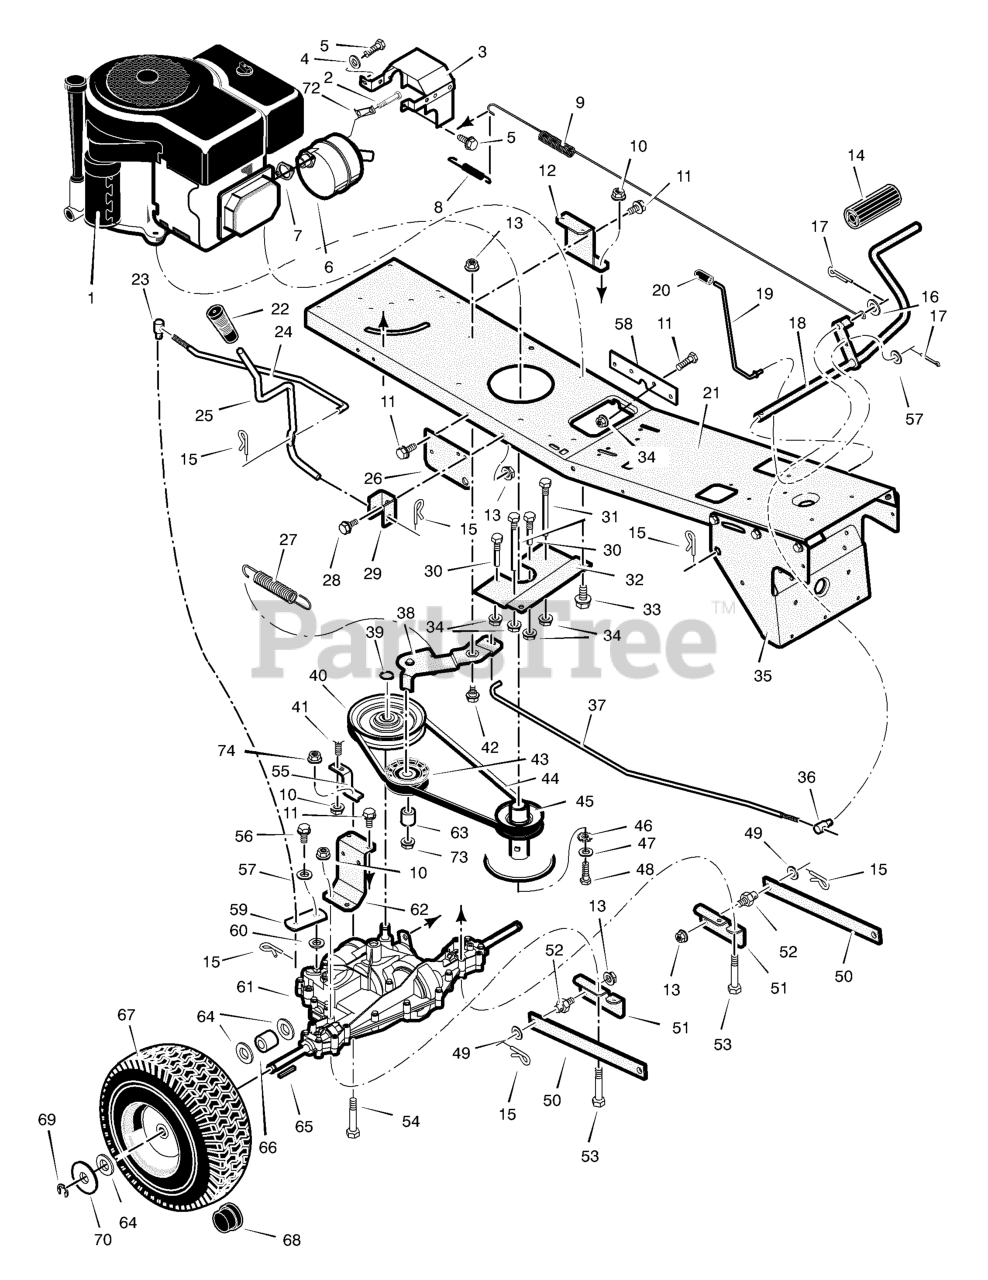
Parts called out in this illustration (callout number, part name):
1	Engine, Briggs & Stratton *
2	Bolt, Hex
3	Shield Assembly, Heat
4	Lockwasher
5	Screw
6	Muffler
7	GASKET, Exhaust
8	Spring, Extension
9	Spring, Extension
10	Nut
12	Bracket, Left Transaxle
13	Nut, Flange
14	Cover, Pedal
15	Pin, Cotter
16	Washer
17	Pin, Cotter
18	Pedal Assembly
19	Rod, Parking Brake
20	Grip, Parking Brake Rod
22	Grip, Shift Lever
23	Nut, Adjusting
24	Link, Shift
25	Lever, Shift
26	Bracket, Lift Pivot
27	Spring, Extension
28	Bolt, Shoulder
29	Bracket, Pivot
30	Guide, Short Belt
31	Guide, Long Belt
32	Plate, Belt Guide
33	Bolt
34	Nut, Flange
35	Bracket, Support
36	Nut, Adjusting
37	Rod, Clutch
38	Clutch Arm Assembly
39	Ring, Retainer
40	Pulley, Drive
41	Bolt, Carriage
42	Bolt, Shoulder
43	Pulley, Idler
44	Belt, Motion Drive
45	Pulley, Split Stack
46	Washer, Star
48	Bolt, Hex
49	Washer
51	Bracket, Rear Hanger
52	Pin, Threaded Shoulder
53	Bolt, Hex
55	Bracket, Torque Reactor
57	Washer, Shift Yoke
58	Support, Frame
59	Yoke, Shift
61	Transaxle, Peerless **
62	Bracket, Right Transaxle
63	SPACER, Rear Wheel
65	Key, Square
66	SPACER, Rear Wheel
67	Wheel, Rear -15"
68	Cap, Hub
72	Lock, Screw
73	Nut
74	Nut
